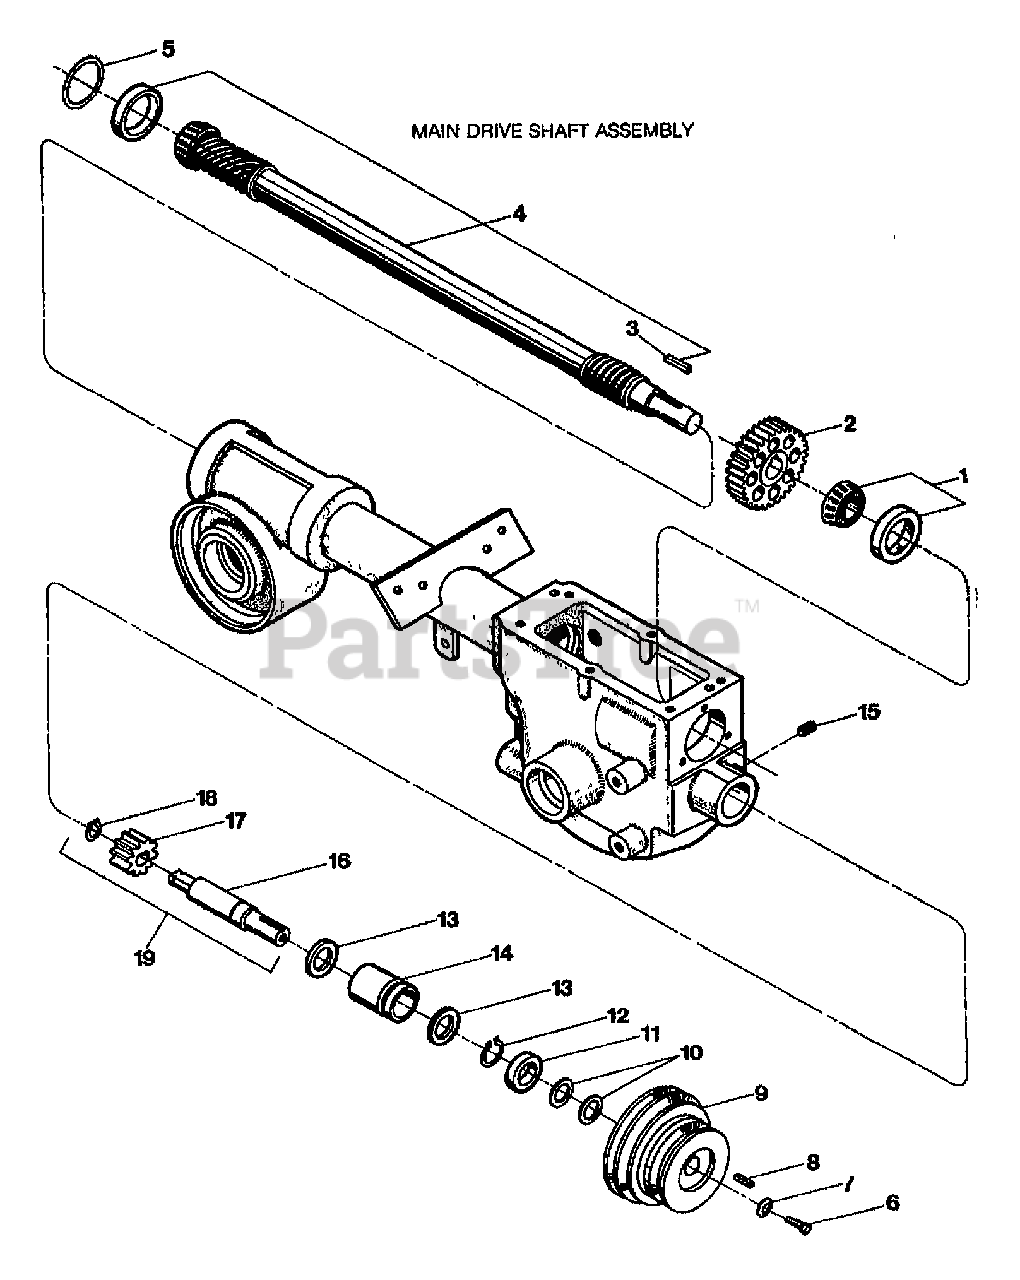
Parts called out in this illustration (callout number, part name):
1	KIT-BRG CONE&RACE-DRIVESHAFT (FRONT OF DRIVE SHAFT)
2	GEAR-SPUR 30 TEETH
3	KEY-.188 SQX1.0
4	KIT-DRIVESHAFT
5	SHIM-1.75X1.5X.01
5	SHIM-1.75X1.5X.03
5	SHIM-1.75X1.5X.005
6	SCR-HH 5/16-24X.75 G5 ZP
7	WASHER-.827X.331X.098
8	KEY-.188 SQX1.0
9	PULLEY-TRANS MACH, 3 GROOOVES (TWO FOR FORWARD SPEEDS; ONE FOR REVERSE SPEED)
10	WASHER # .875 X .65 X .06
11	SEAL-PINION SHAFT PT/85030/00
12	RING-RETAIN EXT .707 ID (SNAP RING)
13	WASHER-1.022X.752X .059
14	BUSHING-1.24X.75X1.8 GRVD
15	SCR-SS 5/16-18X.375
16	SHAFT-PINION(P-V)
17	GEAR-PINION P/M
18	RING-BOWED EXT .461 ID (SNAP RING)
19	PINION W/GEAR&SNAP RING
